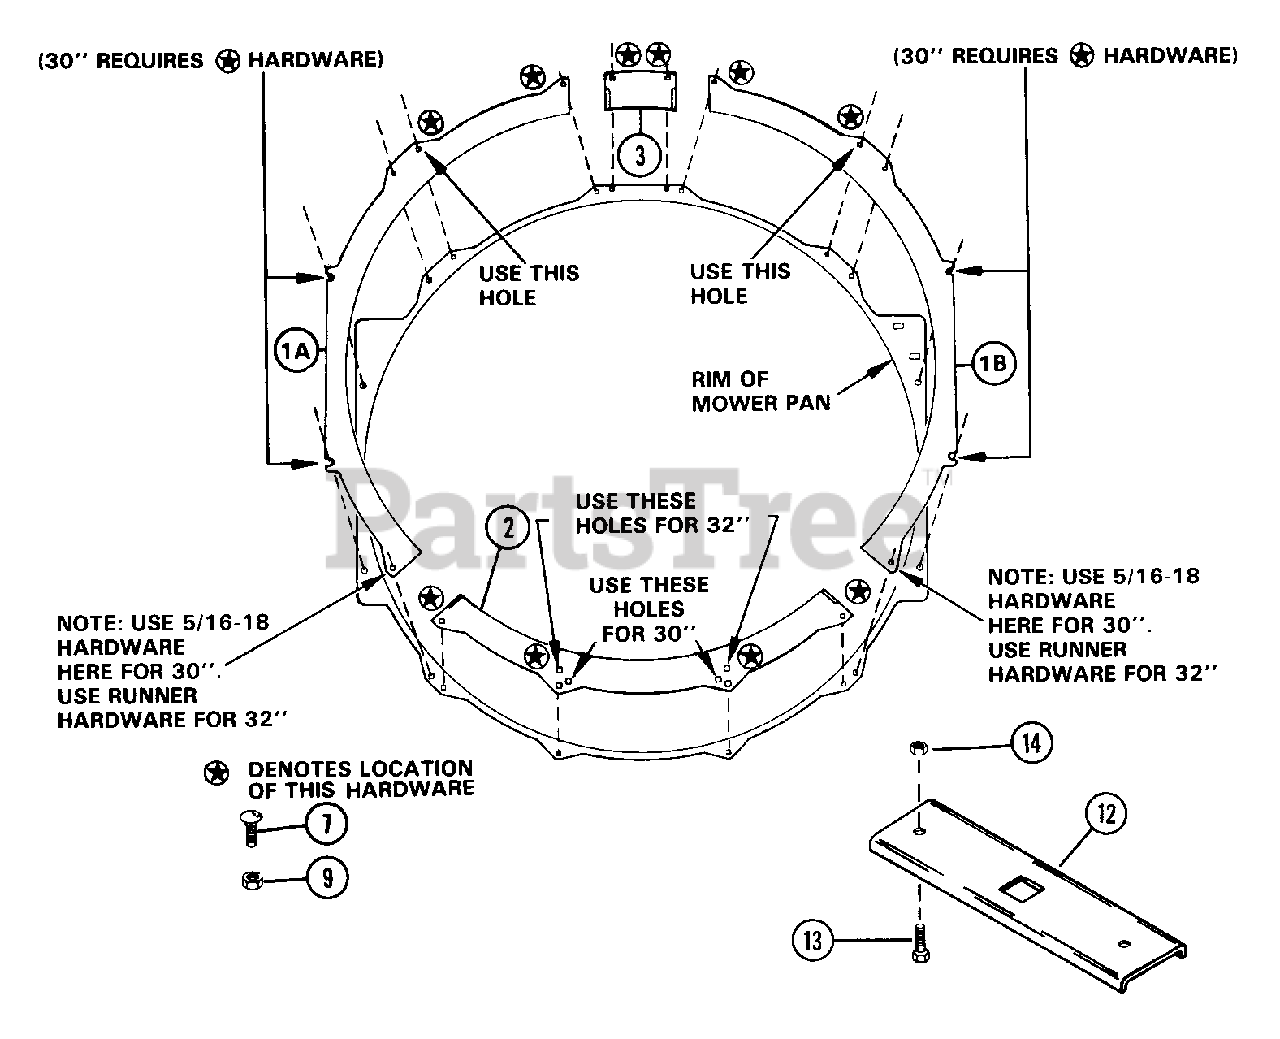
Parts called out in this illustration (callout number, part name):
1A	30 IN FLANGE R H
1B	30 IN FLANGE L H
2	BACK FLANGE
3	FRONT CLAMP
7	BLT-RDHDSQNK .25-20X.62 PL
9	NUT-LK-CTR .250-20 PL
10	BLT-RDHDSQNK .312-18X.62SHTPL
11	NUT-LK .312-18 GR A PL
12	BLADE TRAY
13	BLT-HEX .38-16X1.00 PL GR5
14	NUT-LK TOP .375-16 GR C YWZC
